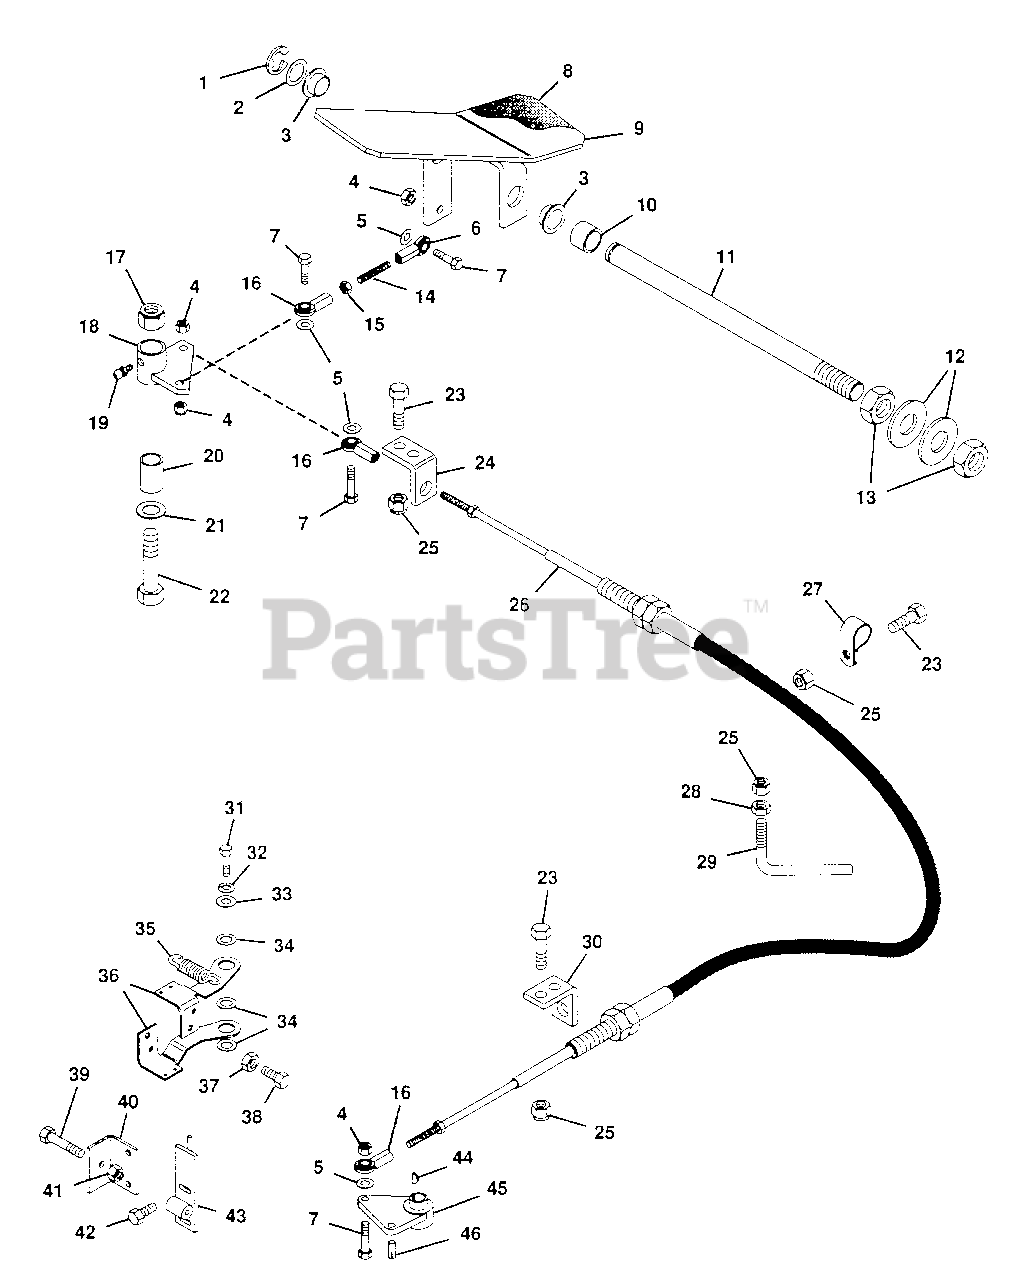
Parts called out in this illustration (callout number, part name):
1	E-RING, .750 SHAFT
2	RACE, BEARING THRUST
3	BUSH., FLG. .764X1.47X.560 NY.
4	NUT, LOCK 1/4-20
5	WASHER, FLAT .281X.625X.065
6	ROD END, L.H.
7	BOLT, HEX 1/4-20X1.25
8	COVER, PEDAL
9	WELDMENT, PEDAL
10	BUSH., ST. .782X1.00X.710 STL.
11	SHAFT, PEDAL
12	WASHER, FLAT .812X1.496X.134
13	NUT, JAM 3/4-16 HEX
14	ROD
15	NUT, JAM 1/4-28 HEX
16	ROD END, FEMALE 1/4-28
17	NUT, LOCK 1/2-13
18	WELDMENT, LEVER
19	FITTING, LUBE 1/4-28
20	BUSH., ST. .562X.855X1.56 STL.
21	WASHER, FLAT .500X1.250X.083
22	BOLT, HEX 1/2-13X2.50
23	BOLT, HEX 3/8-16X1.00
24	BRACKET, CABLE
25	NUT, LOCK 3/8-16
26	CABLE, FWD-REV
27	CLAMP, STEEL .625
28	NUT, JAM 3/8-16 HEX
29	ROD, CABLE GUIDE
30	BRACKET, CABLE
31	BOLT, HEX 1/4-20X1.50
32	WASHER, LOCK 1/4 REG.
33	WASHER, FLAT .265X1.250X.063
34	WASHER
35	SPRING, EXT. .62X.75X11.8 RATE
36	LEVER, NEUTRAL
37	NUT, JAM 5/16-24 HEX
38	BOLT, HEX 5/16-24X.75
39	BOLT, HEX 5/16-18X1.75
40	BRACKET
41	NUT, LOCK 5/16-18
42	SCREW, TAPTITE 5/16-18X.75
43	WELDMENT, NEUTRAL STOP
44	KEY, WOODRUFF .125X.50 HRD #3
45	ARM, TRANSMISSION CONTROL
46	PIN, GROOVE
